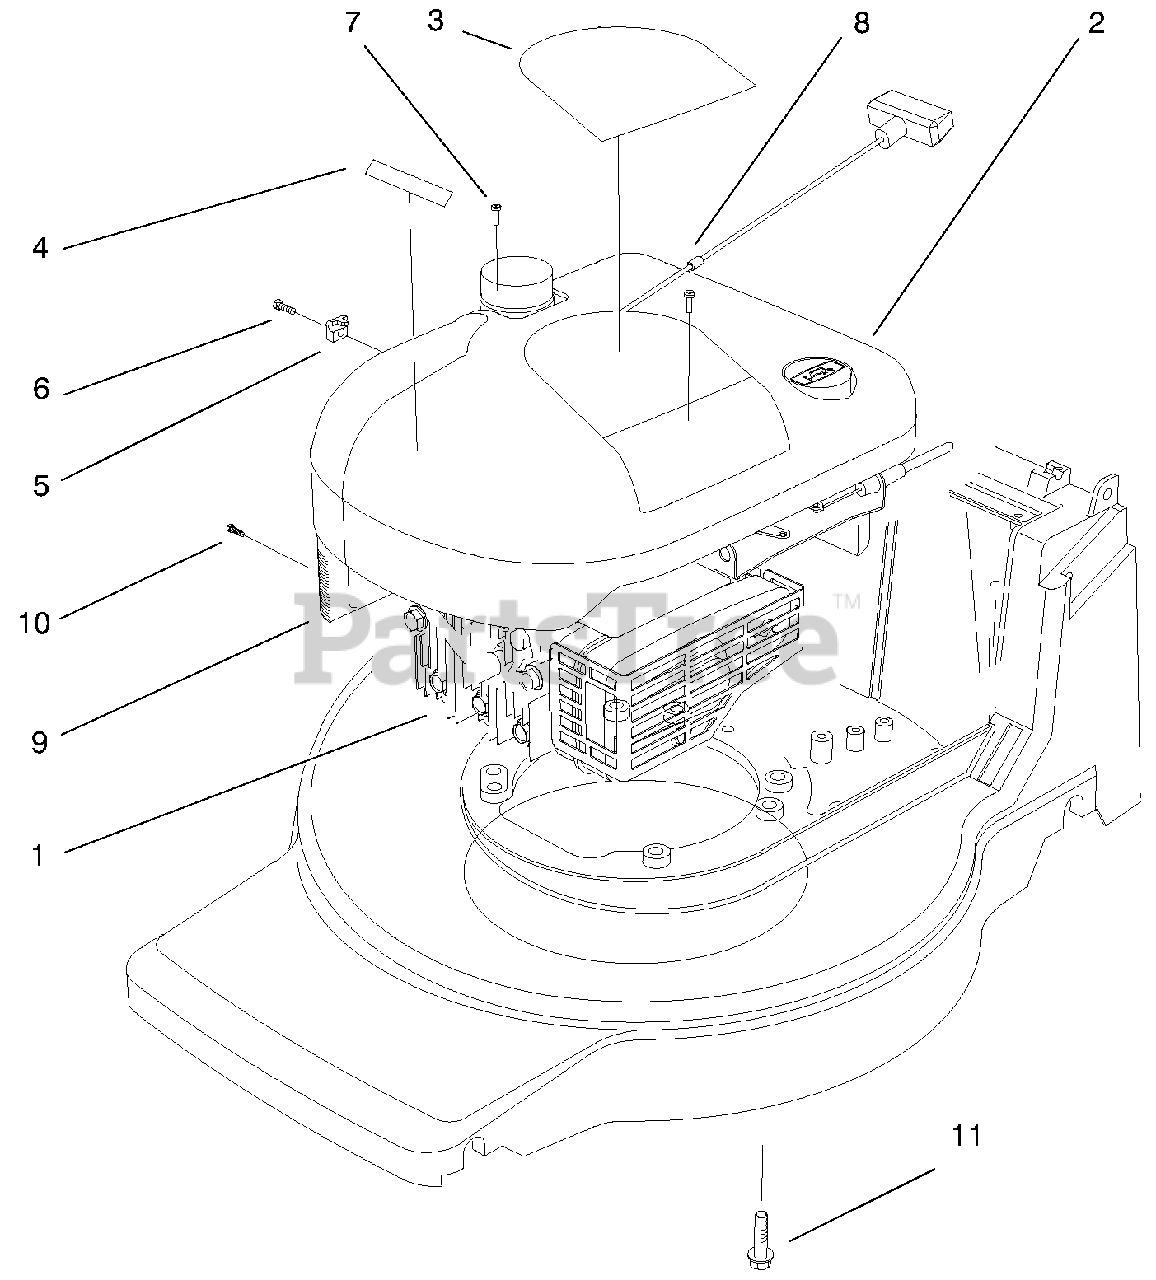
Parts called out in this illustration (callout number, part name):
1	Engine
2	Shroud-Engine
3	Decal-Recoil
4	Applique-Shroud
5	Clamp-Casing
6	Screw-Clamp
7	Screw-Mtg
8	Rope-Stop
10	Screw-Air Cleaner
